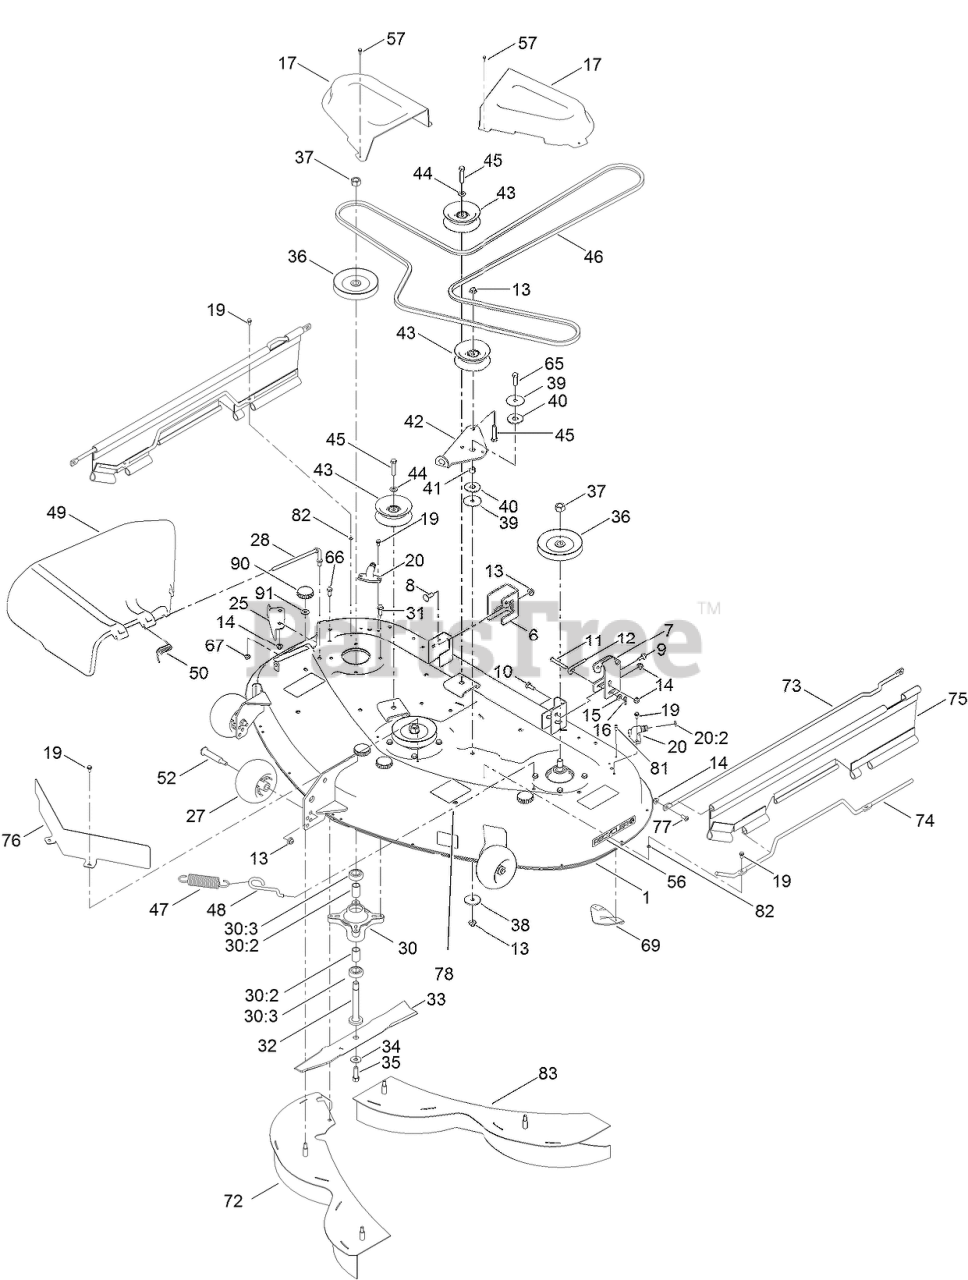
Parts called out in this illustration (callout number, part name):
1	50 INCH DECK AND DECAL ASM
6	Bracket-Hanger, RIGHT REAR
7	Bracket-Hanger, LEFT REAR
10	SCREW-CARR
11	Pin-Clevis
13	NUT-HF, NI
14	NUT-HF
15	WASHER-PLAIN
16	PIN-HAIR
17	COVER-BELT
19	SCREW-HWH
20	FITTING-WASHOUT
20:2	O-RING
25	BAFFLE-CUTOFF
27	ROLLER-SCALP, ANTI
30	SPINDLE ASM
30:2	SPACER
30:3	BEARING-BALL
31	SCREW-TAPTITE
32	SHAFT-SPINDLE
33	BLADE-MULCH, 17.50 INCH
34	WASHER-BELLEVILLE
35	SCREW-HH
36	PULLEY
37	Nut-Hex
38	Washer
39	Nut-Hex
40	WASHER-FRICTION, COMPOSITE
41	SPACER
42	ARM-IDLER
43	PULLEY-IDLER, FLAT
44	WASHER-FLAT
45	SCREW-HH
46	V-BELT
47	SPRING-EXTENSION
48	HOOK-RETURN SPRING
49	DEFLECTOR
50	SPRING-TORSION
52	BOLT-SHOULDER
56	DECAL-RECYCLER
57	SCREW-TAPTITE
65	SCREW-HH
66	SCREW-HH
69	PLATE-KICKER
72	RH BAFFLE ASM
73	ROD SUPPORT, UPPER
74	ROD SUPPORT, LOWER
75	GUARD-SIDE
76	SHIELD-FRONT
77	SCREW-HSBH
78	NUT-RETAINING
81	SCREW-PLASTIC, PPH
82	NUT-RETAINING
83	LH BAFFLE ASM
91	WASHER-BELLEVILLE
